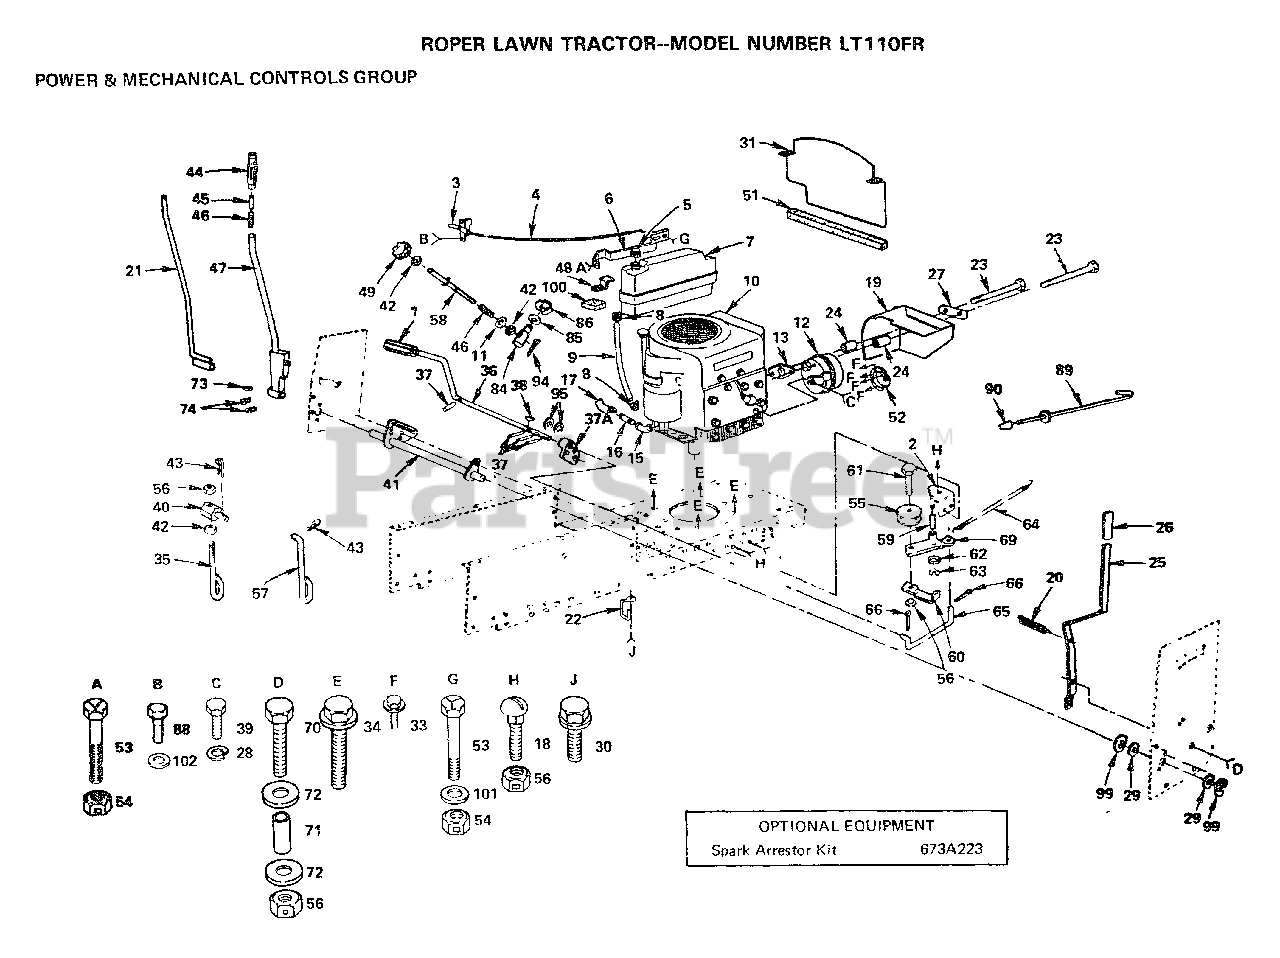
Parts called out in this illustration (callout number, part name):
1	PEDAL COVER T
6	SUPPORT-TANK LT
9	HOSE T
11	WASHER
12	MUFFLER LTV
15	STREET ELBOW LT
16	PIPE NIPPLE
17	ELBOW
18	BOLT
19	BAFFLE ASSY LT
20	"SPRING.EXT.8.5"""
21	ROD ASSY-LEVER LT
23	BOLT YT
24	SPACER LT
27	CLIP-MUFFLER LT
28	LOCKWASHER
29	WASHER
30	SCREW
32	WASHER
34	SCREW
35	LINK LIFT LT
36	FOOT SHAFT PEDAL
37A	ARM BRAKE LT
39	BOLT
44	GRIP
46	SPRING T
47	LEVER ASSY LT
48	BRACE-TANK LT
52	DEFLECTOR.222573
53	BOLT
57	LIFT LINK LT
58	ROD ADJUST LT
59	"LY, BEARING"
62	WASHER T
63	KLIP RING
64	"SPRING, RETURN LT"
65	"LINK, CLUTCH T"
66	COTTER PIN
85	WASHER
86	KLIP RING
88	SCREW
90	PLUNGER CAP T
99	RING
100	PAD-SPACER T
101	WASHER
102	WASHER
